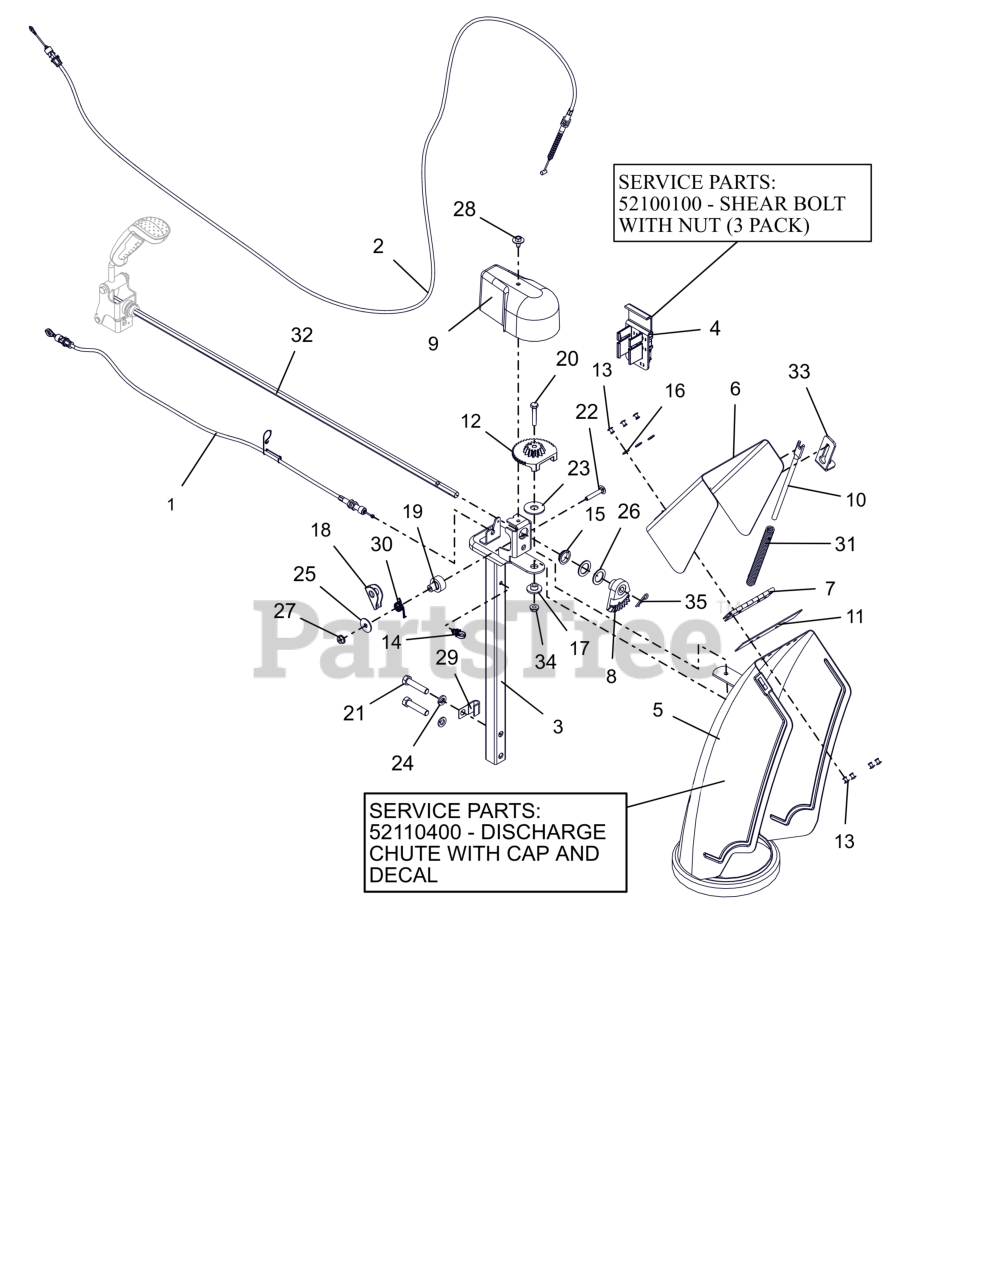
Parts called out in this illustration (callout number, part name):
1	CABLE, CHUTE LOCK, PRO
2	CABLE, DEFLECTOR - DELUXE
3	PEDESTAL, CHUTE - QUICK STICK
4	HOLDER W LARGE SHEAR BOLT /NUT
4	SHEAR BOLT SERVICE ASSEMBLY
5	CHUTE,DISCHARGE,NOTCHED,QT
5	CHUTE, DISCHARGE W/CAP
6	CAP, LARGE REMOTE W/DECAL
8	GEAR, CHUTE-ACTUATION
9	COVER, CHUTE GEAR
10	ROD, DEFLECTOR CAP
11	CAP SEAL 5.50
12	GEAR, CHUTE
13	RVT, POP .1875 ZCC
14	CLIP, CABLE GUIDE
15	BUSHING, POLYLINER-.75 SNAPIN
16	WSHR,FLT .196X.500X.066 ZCC
17	BSHG-FLG .265X.477X.375X1.00
18	ARM, LOCKING
19	BUSHING, LOCK ARM
20	BLT, HEX .25-20X1.50 G5 ZCC
21	BLT, HEX .38-16X1.75 G5 ZCC
22	BLT, RHSN .25-20X1.50 G5 ZCC
23	WSHR-FLT-NYL .515X1.375X.093
24	WSHR,LK-REG .375X.094 ZCC
25	WSHR,FLT .281X1.000X.063 ZCC
26	WSHR, FLT .754X1.125X.062 ZCC
27	NUT-LK-CTR-FLG .25-20 ZC120
28	SCR, TAP .25-20X.50 LG HWH ZCC
29	J-CLAMP
30	SG-TORS
31	SG-COMP .08X.40X6.50 14#/IN
32	ROD, HEX - CHUTE ROTATION
33	BRACKET, ANCHOR-CHUTE CABLE
34	NUT-LK-CTR-FLG .25-20 ZC120
35	PIN, HAIR #213 .08X1.19 ZCC
